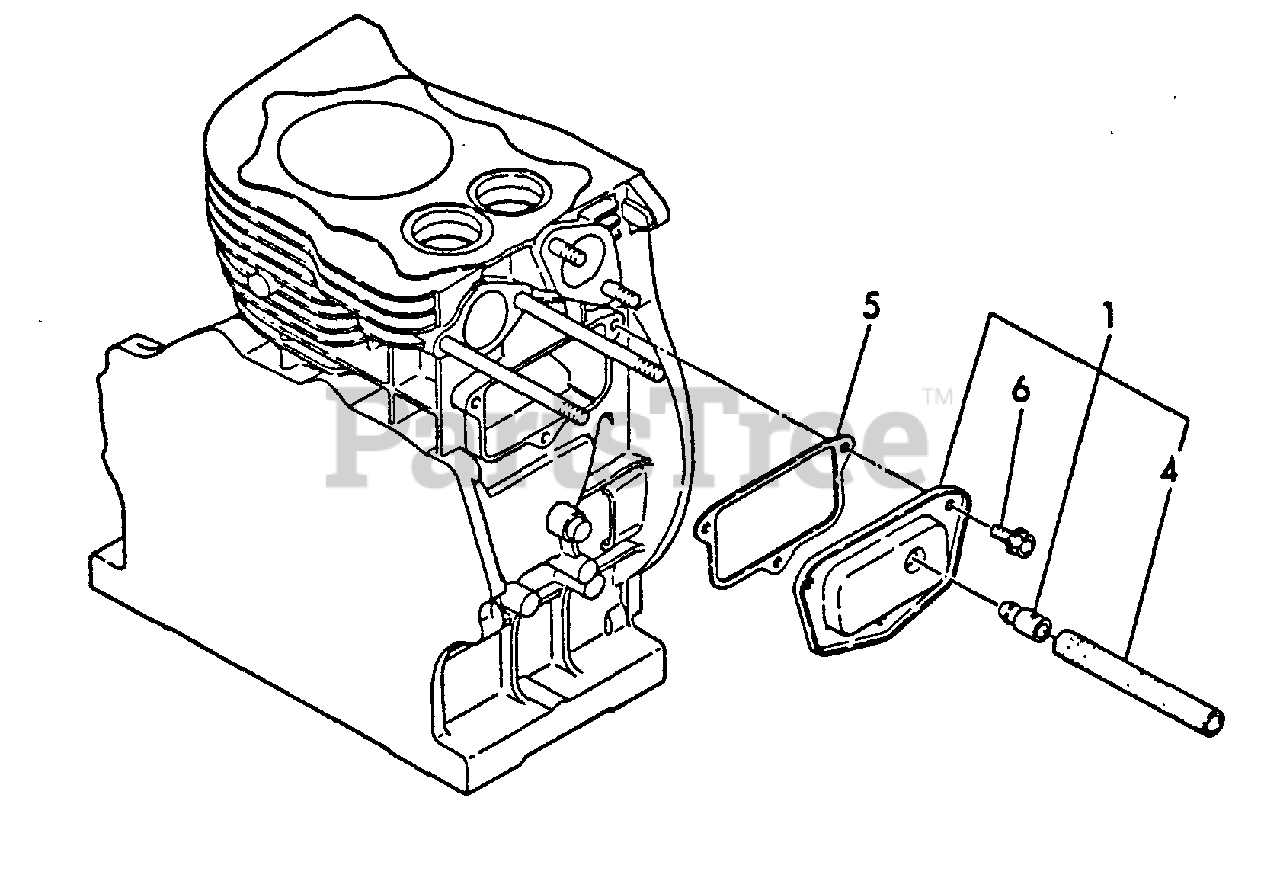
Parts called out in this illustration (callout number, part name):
1	BREATHER ASSY
4	PIPE, BREATHER
6	BOLT - 6×8 -- PLATED
